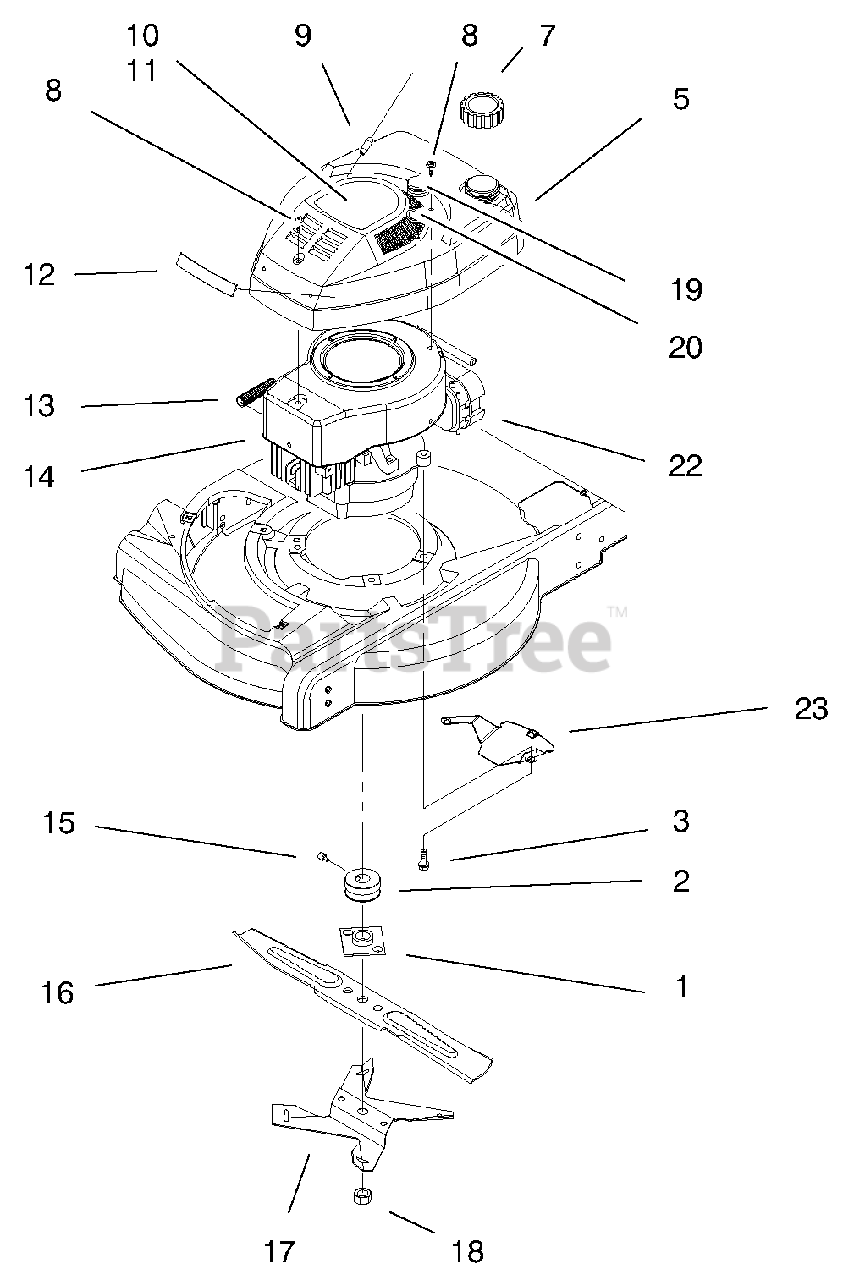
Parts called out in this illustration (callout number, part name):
1	Plate & Collar Assembly
2	Pulley-Engine (Model No. 10304 Only)
3	Screw-Engine
5	Tank & Shroud Assembly
7	Fuel/Oil Cap Assembly
8	Screw-Sems
9	Rope-Stop
10	Decal-Recoil (Model No. 10227 Only)
11	Decal-Recoil (Model No. 10304 Only)
12	Applique-Shroud
13	Spring-Compression
14	Engine Assembly
15	Screw-Set (Model No. 10304 Only)
16	Blade-21"
17	Fan-Mulching
18	Nut-Blade
19	Bulb-Primer
20	Body-Primer
22	Line-Gas
23	Shield-Grass (Model No. 10304 Only)
